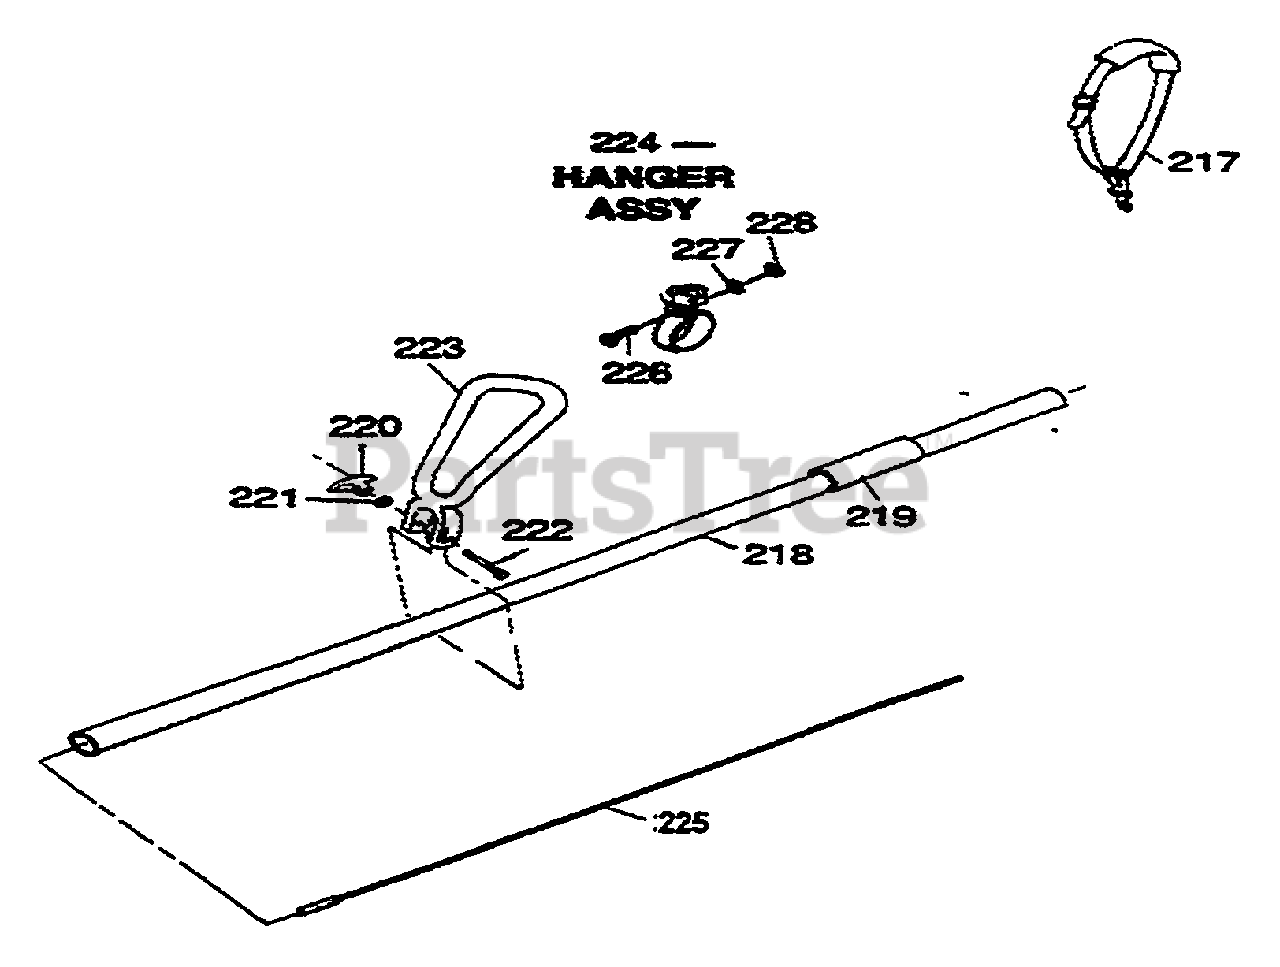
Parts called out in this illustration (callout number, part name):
217	HARNESS
218	TUBE ASSY
220	KNOB
222	BOLT
223	ASSIST HANDLE
224	HANGER ASSY
225	CABLE, FLEX
